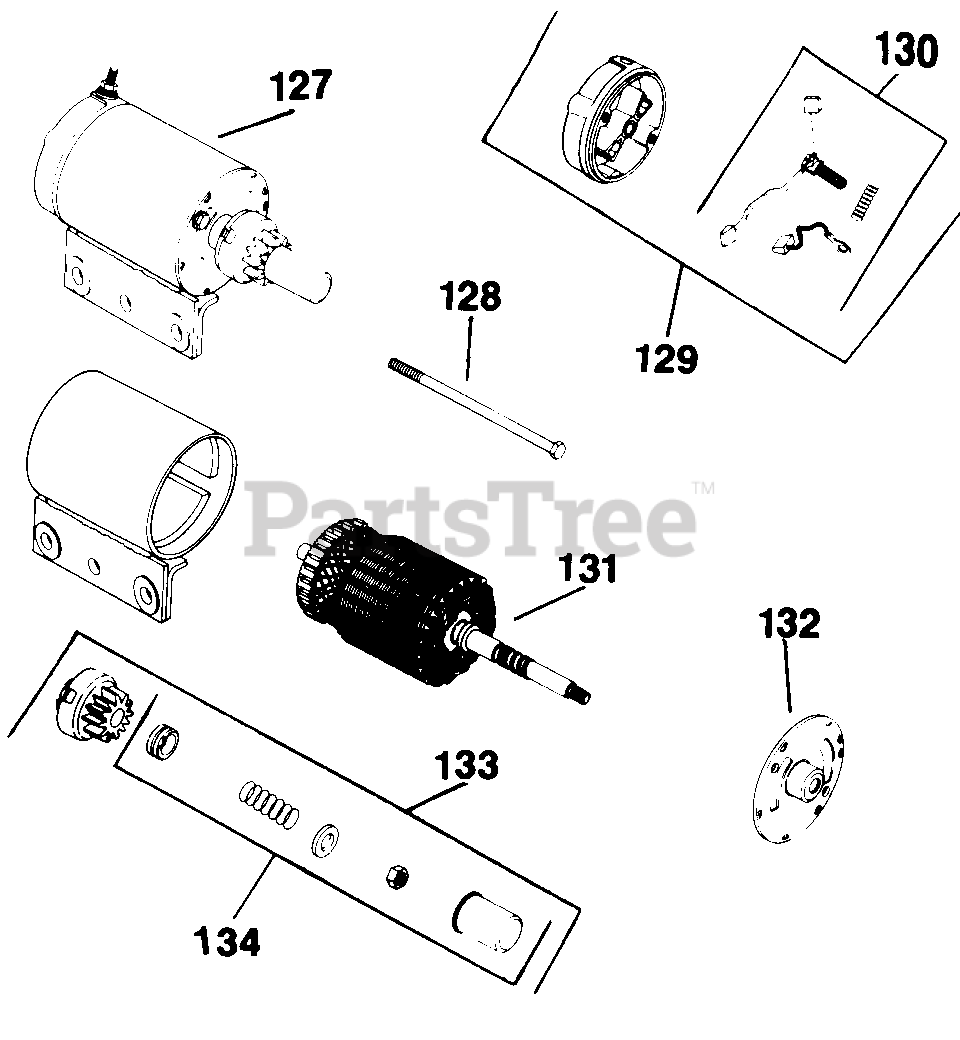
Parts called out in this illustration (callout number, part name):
127	STARTER - USE 45 098 11
129	CAP - DISCONTINUED
130	KIT - USE 52 755 15
131	ARMATURE - DISCONTINUED
132	CAP - USE 45 081 05
133	DRIVE KIT - USE 45 755 16
